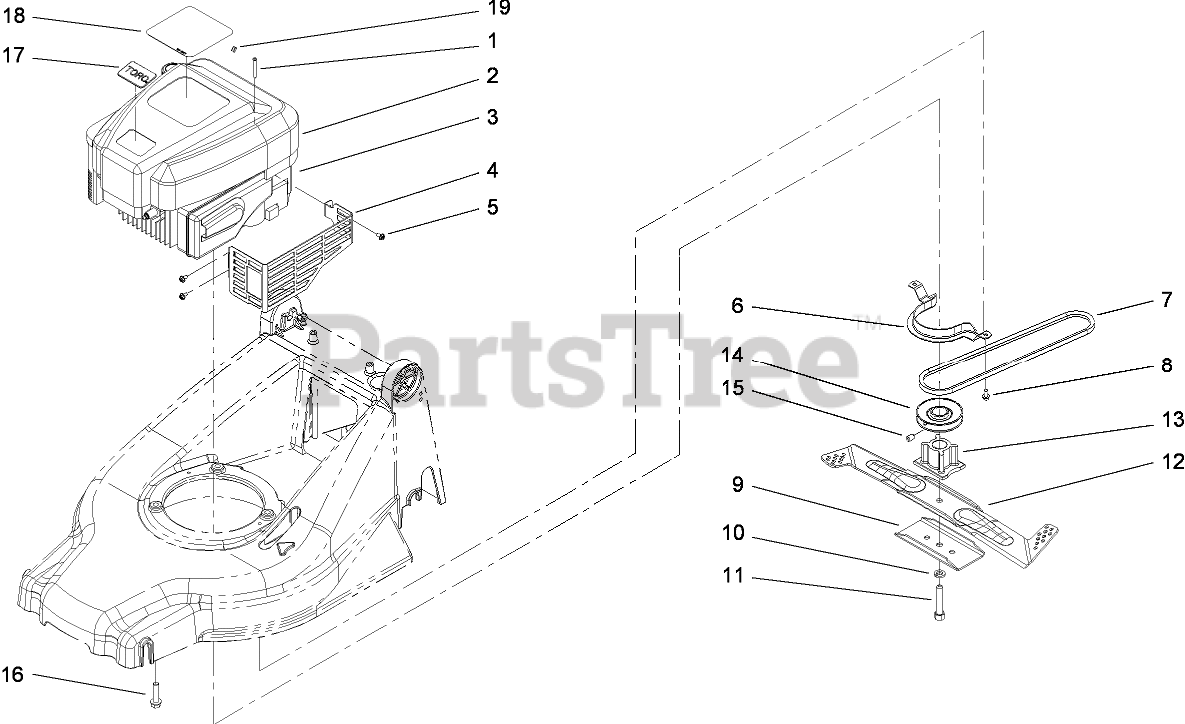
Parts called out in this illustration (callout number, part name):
1	SCREW-PPH
2	SHROUD-ENGINE
4	SHIELD-MUFFLER
5	SCREW-HWH
6	GUIDE-BELT, ENGINE
7	V-BELT
8	SCREW-HWH
9	STIFFENER-BLADE
10	WASHER-LOCK
11	BOLT-BLADE
13	RETAINER-BLADE
14	PULLEY ASM
15	SCREW-SET
16	SCREW-HWH
17	Decal
18	DECAL-ENGINE
19	STOP-ROPE
